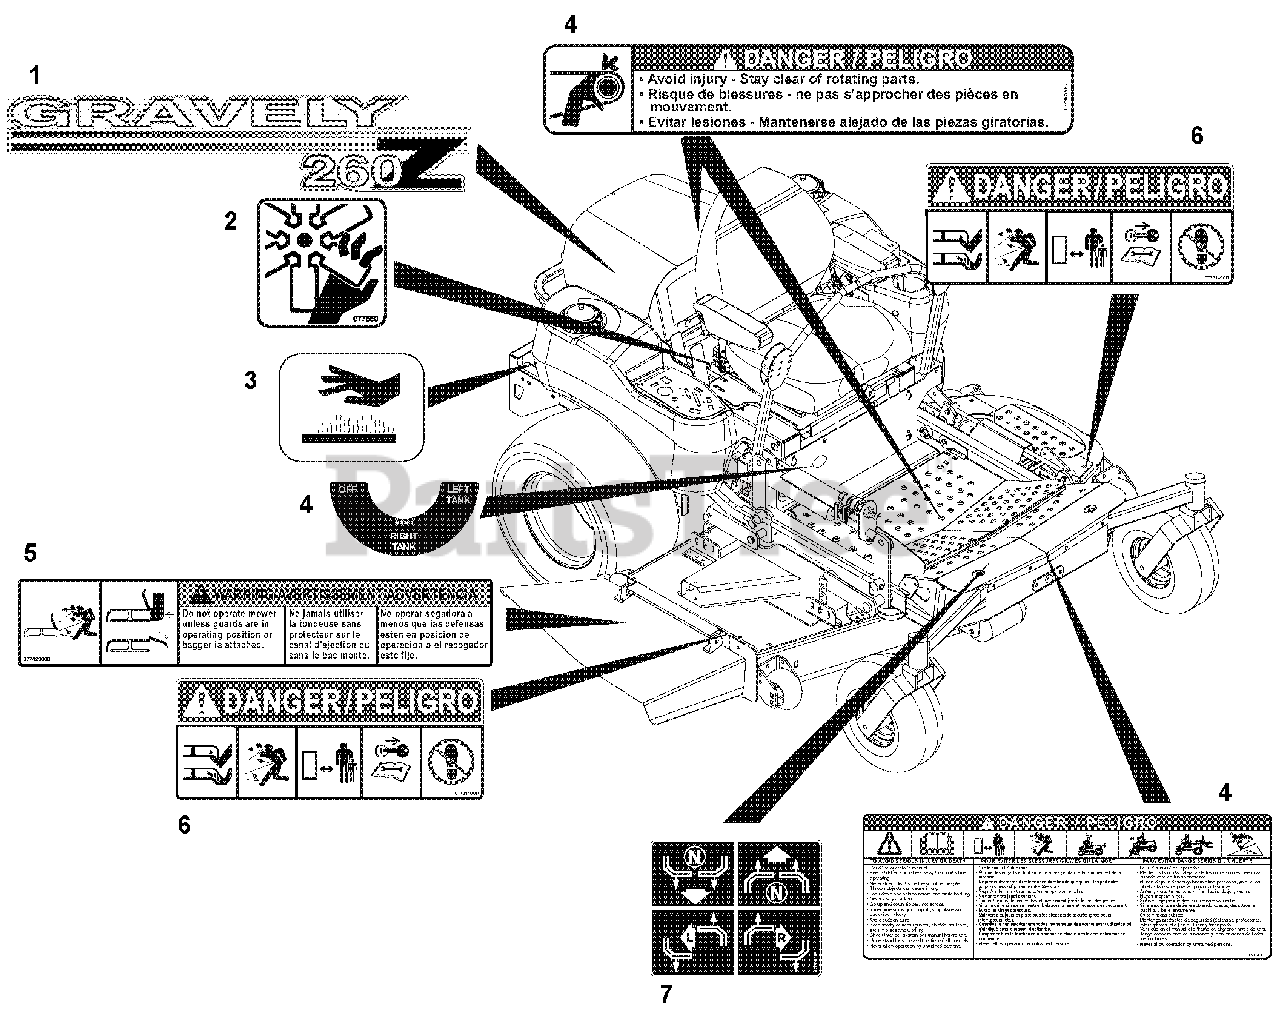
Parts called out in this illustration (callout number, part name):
1	Decal, PM-260Z Hood (046, 047, 067, 068, 085, 088, 089, 105, 106)
2	Decal, Danger Fan
3	Decal-Hot Surface
4	Set, Decal-Common Danger/Fuel
5	Decal, Warning
6	Decal, Mower Pan Head Danger
7	Decal-Instructional
